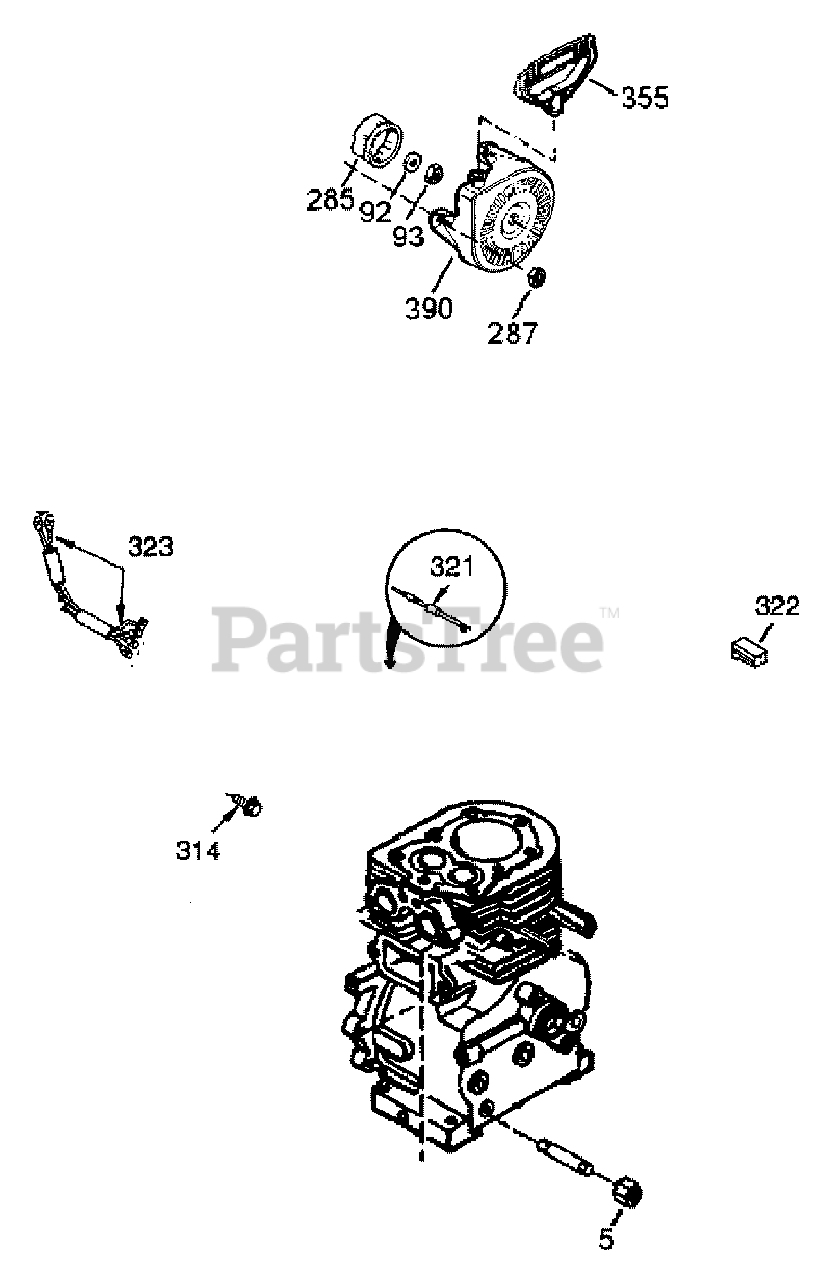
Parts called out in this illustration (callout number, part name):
5	Extension Cap
92	Lock Washer
93	Flywheel Nut
130C	Screw, 5/16-18 x 1-25/32"
285	Starter Cup
287	Nut & Lock Washer, 1/4-28
314	Screw, 1/4-20 x 3/4"
322	Connector Body
355	Starter Handle (Mitten Grip)
370I	Warning Decal
390	Rewind Starter
